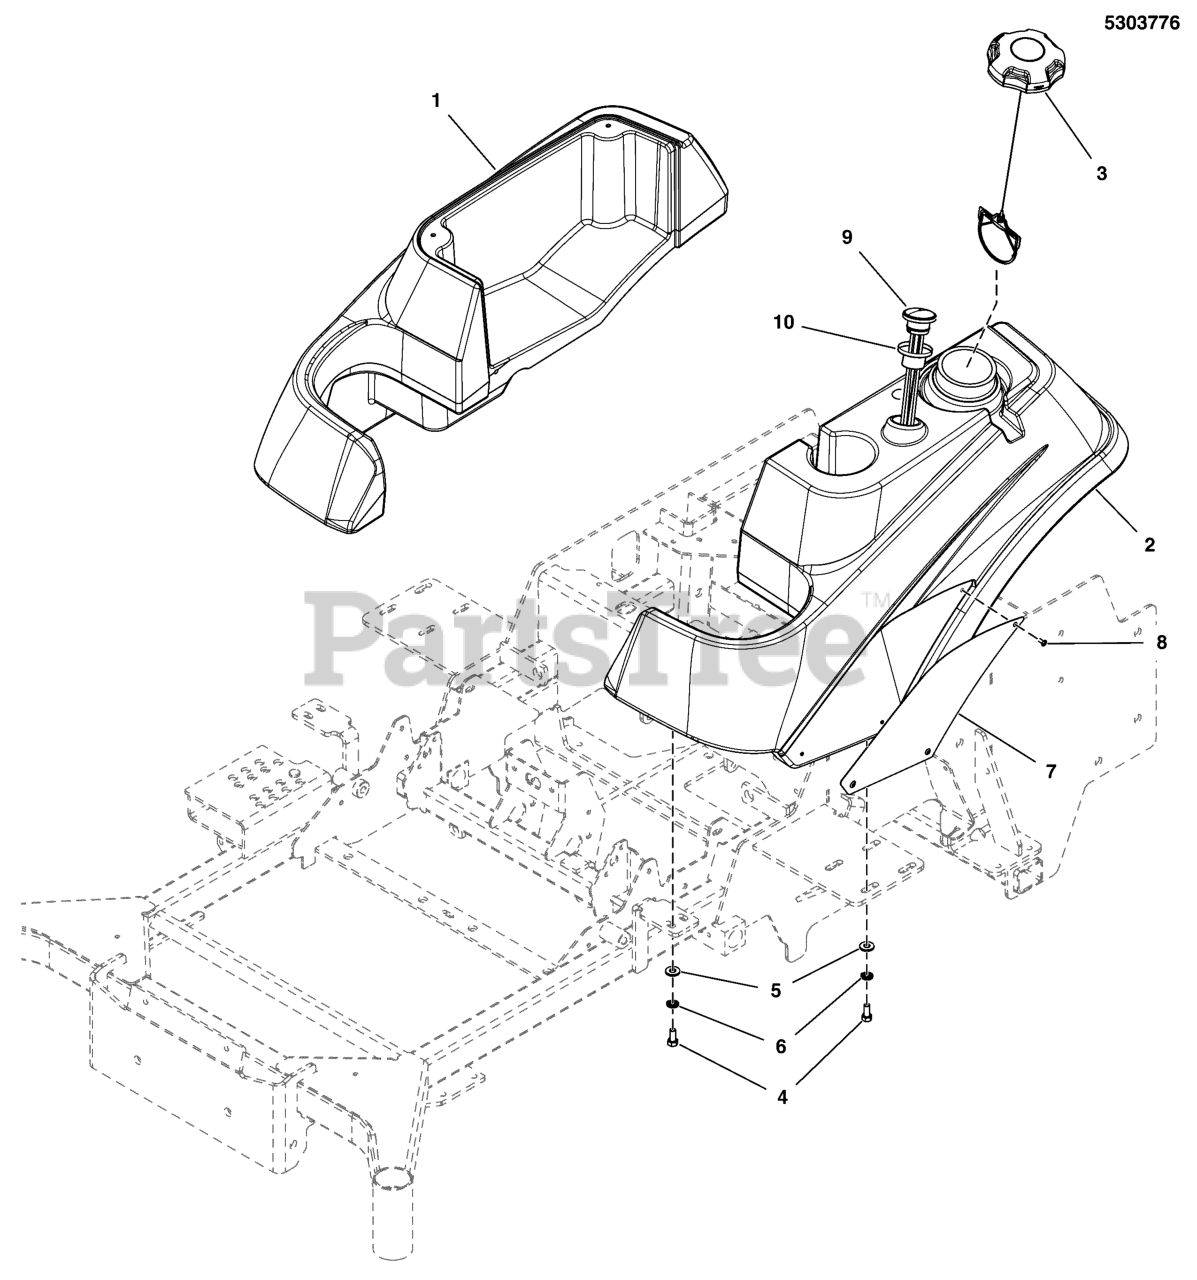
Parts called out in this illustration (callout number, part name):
1	TANK, FENDER, 1500Z - RH
2	TANK, FUEL, IS500 & IS1500 - LH
3	FUEL CAP, 3-1/2", MANAGED VENT OUT, 12"
4	BOLT, 5/16-18 X 3/4 GD5
5	WASHER, 5/16 F436 FLAT
6	WASHER, 5/16 LOCK CZ
7	PLATE, BADGE - IS1500 - RED
8	SCREW, #10-24 X 3/8 ALLEN BHBZ
9	GAUGE, FUEL, 12
10	GROMMET, FUEL GAUGE
